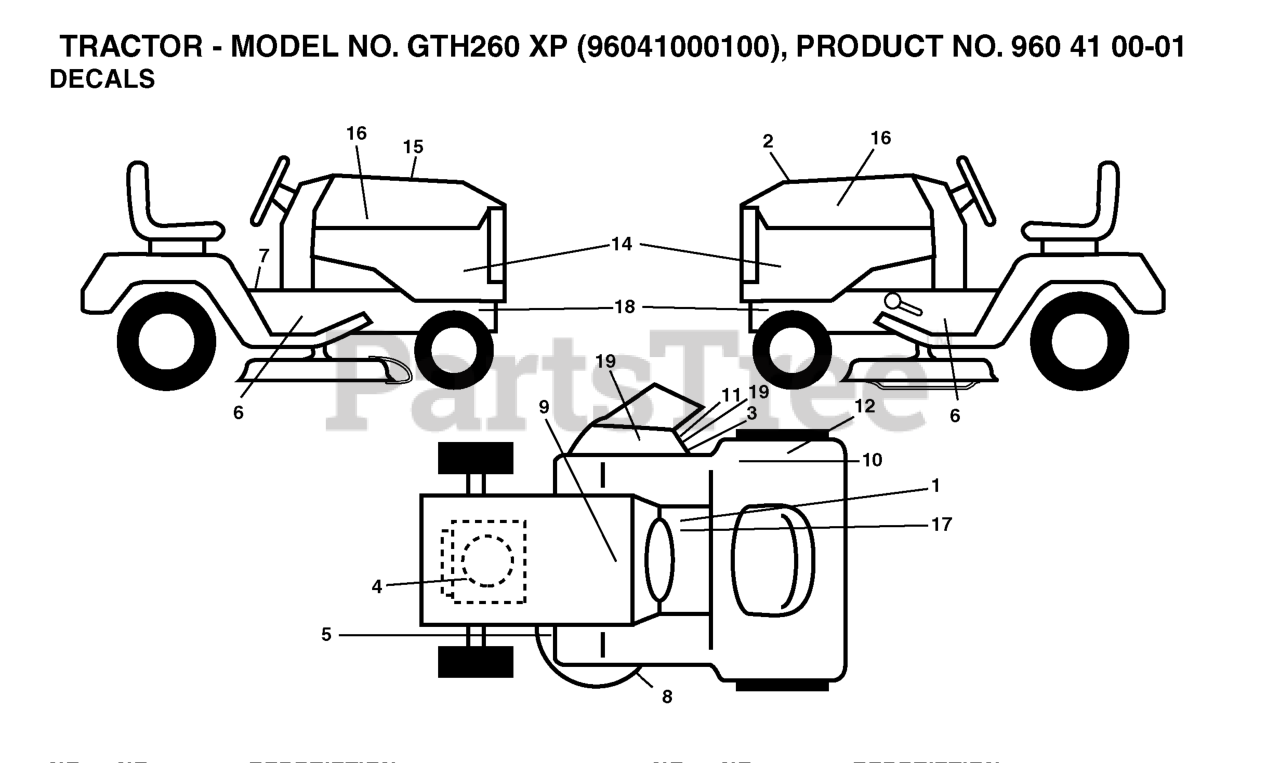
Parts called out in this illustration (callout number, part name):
1	DECAL
2	DECAL.HOOD.TOP.INSERT.
3	DECAL, DEFLECT WARNING
4	DECAL
5	DECAL
7	LABEL
8	DECAL.MOWER.SCH.48/54
9	DECAL BTRY SYMBOLS
10	DECAL.FENDER
11	DECAL.INTERNATIONL.CUTFINGER
12	DECAL
16	DECAL.HOOD.NAMELOGO.HUSQ
17	DECAL PARK BRAKE
